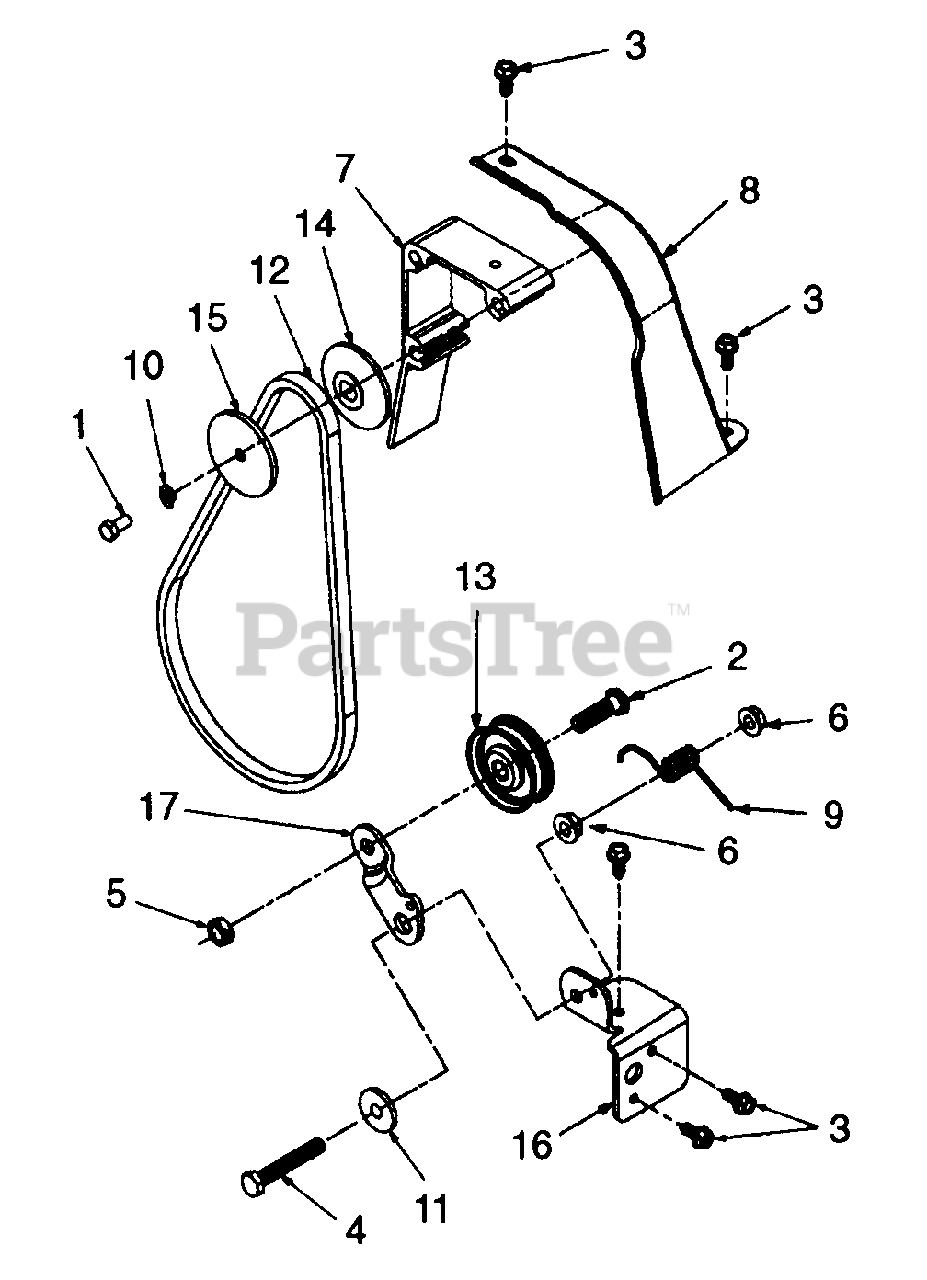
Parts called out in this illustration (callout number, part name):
1	Screw, Hex Cap, 1/4-28 x .50
2	Screw, Hex Cap, 3/8-16 x 1.25
3	Screw, Hex Wash Hd Tapp. 1/4 14 x .625
4	Screw, Hex Cap, 5/16-18 x 2.0
5	Nut, Hex Cent-L Jam, 3/8-16
6	Nut, Hex Flange Lock, 5/16-18
7	Adapter, Engine Mtg
10	Washer, Lock, 1/4
11	Shoulder Spacer, .50 ID x .27 Lg
12	V-Belt, 3/8 x 29.0 Lg
13	Pulley, Flat Idler
14	Pulley Half, 2.0 Dia
15	Pulley Half, 2.0 Dia
16	Bracket, Idler Pivot
17	Bracket, Idler
